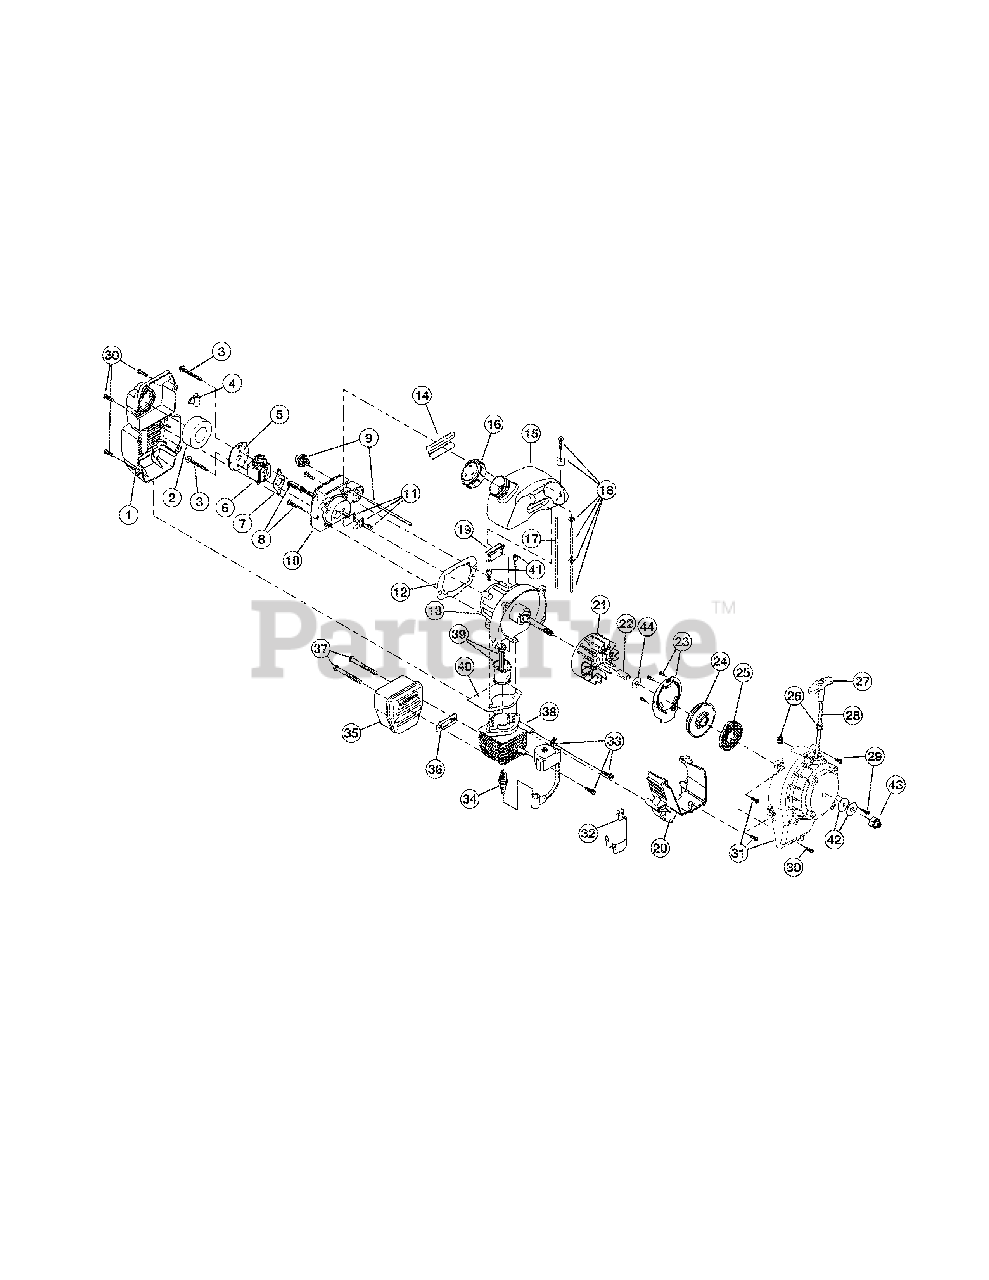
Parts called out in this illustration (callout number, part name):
1	Muffler Cover Assembly (includes 2 & 30)
2	Air Cleaner Filter
3	Carburetor Mounting Screw
4	Choke Knob
5	Choke Plate
6	Carburetor Assembly (includes 7 & 18)
7	Carburetor Gasket
8	Carb Mount Screw
9	Primer & Hose Assembly
10	Carb Mount Assembly (includes 8, 11 & 12)
11	Reed Assembly
12	Carburetor Mount Gasket
13	Crankcase Service Assembly (includes 8)
14	Rear Mounting Pad
15	Fuel Tank Assembly (includes 16-18)
16	Fuel Cap
17	Fuel Return Line
18	Fuel Line Assembly
19	Front Mounting Pad
20	Shroud Extension (includes 30)
21	Flywheel Assembly
22	Spacer
23	Pulley Retainer
24	Recoil Pulley Assembly (includes 28 & 44)
25	Recoil Spring
26	Rope Guide
27	Pull Handle
29	Housing Screw
30	Cover Screw
31	Starter Housing Assembly (includes 23-30 & 44)
32	Wire Lead
33	Module Assembly
34	Spark Plug
35	Muffler Assembly (includes 36 & 37)
36	Exhaust Gasket
37	Muffler Mounting Bolt Set
38	Cylinder Assembly (includes 40 & 41)
39	Piston and Rod Assembly
40	Cylinder Gasket
41	Cylinder Bolt
42	Washer
43	Crankshaft Extension
44	Palnut
